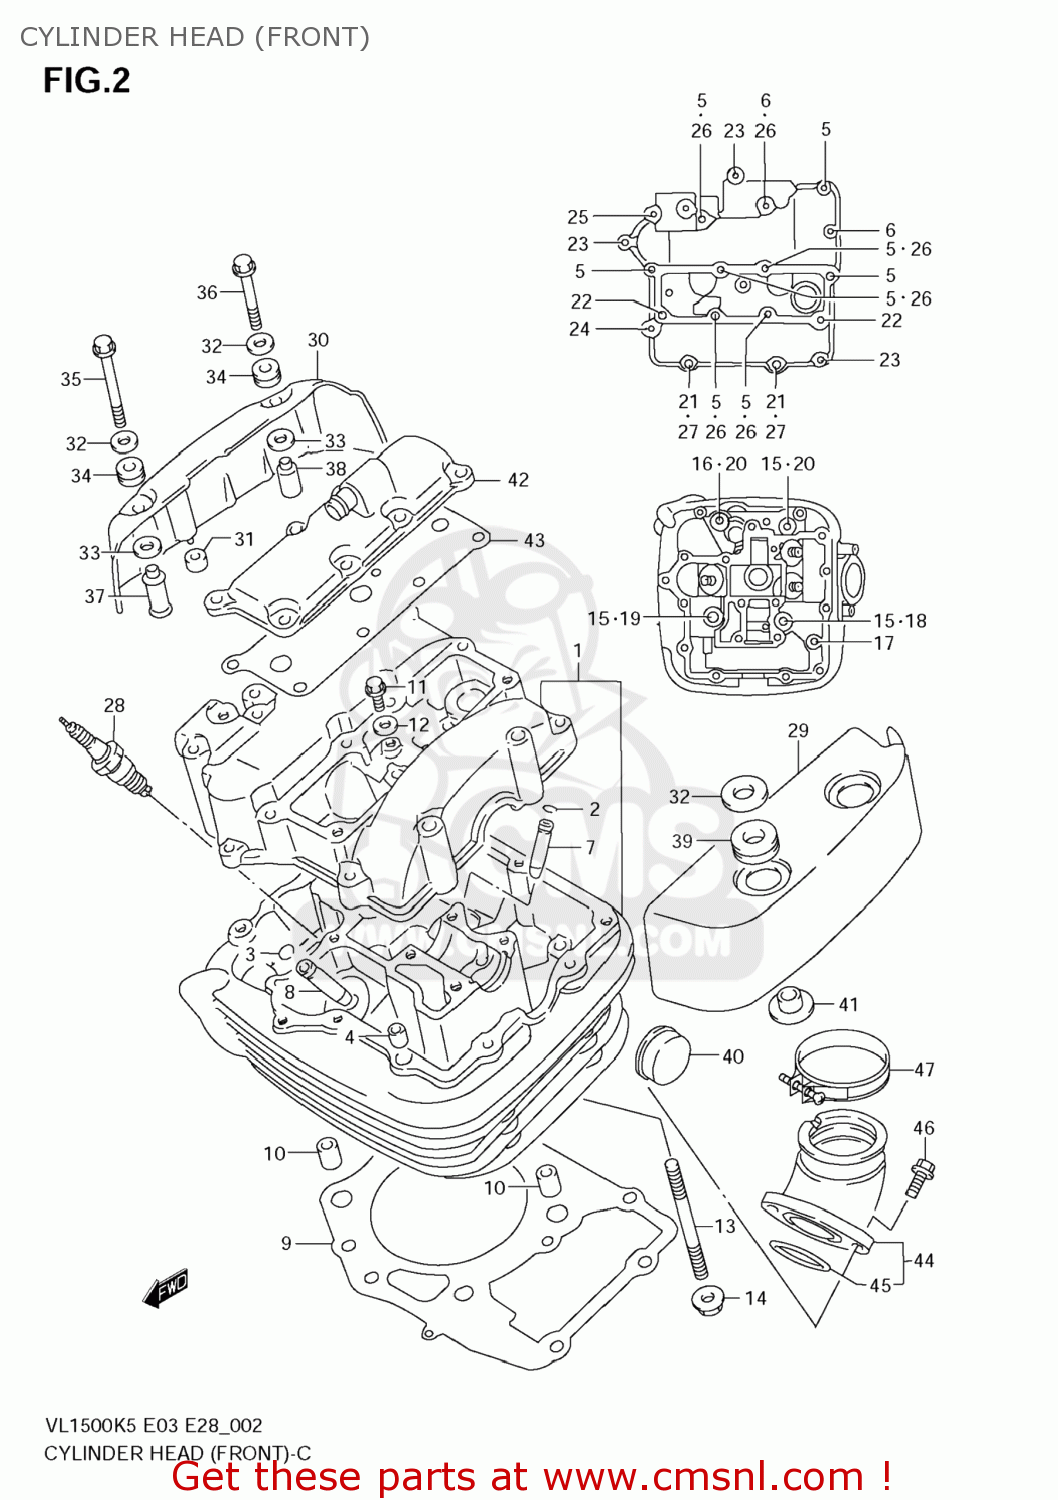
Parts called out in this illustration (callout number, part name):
1	HEAD ASSY,CYLINDER FR
2	RING,SNAP
3	RING,SNAP
4	PIN(6.2X8X11)
5	BOLT(6X60)
6	BOLT(6X55)
7	GUIDE,INTAKE VALVE
8	GUIDE,INTAKE VALVE
9	GASKET,CYLINDER HEAD FR (NAS)
10	PIN
11	BOLT
12	GASKET(6.2X13X1.2) (NAS)
13	BOLT,STUD
14	NUT
15	WASHER(10.5X22X2.3)
16	GASKET(10.5X22X2) (NAS)
17	BOLT(8X70)
18	BOLT(10X180)
19	BOLT(10X190)
20	BOLT(10X200)
21	BOLT(8X268)
22	BOLT
23	BOLT
24	BOLT
25	BOLT
26	GASKET(5.8X13X1.2) (NAS)
27	WASHER(8.5X24X1.6)
28	SPARK PLUG X22E
29	CAP,CYLINDER HEAD COVER FR,L
30	CAP,CYLINDER HEAD COVER FR,R
31	CUSHION,R CAP
32	WASHER(6.5X18X1.6)
33	WASHER(9.5X20X1)
34	CUSHION
35	BOLT
36	BOLT
37	SPACER,CYL HEAD COVER CAP NO.1
38	SPACER,CYL HEAD COVER CAP NO.2
39	CUSHION
40	PLUG(OD:30)
41	BUSH
42	COVER,BREATHER
43	GASKET,BREATHER COVER (NAS)
44	PIPE ASSY,INTAKE FR
45	O RING(D:1.9,ID:40.7)
46	BOLT(6X16)
47	CLAMP
